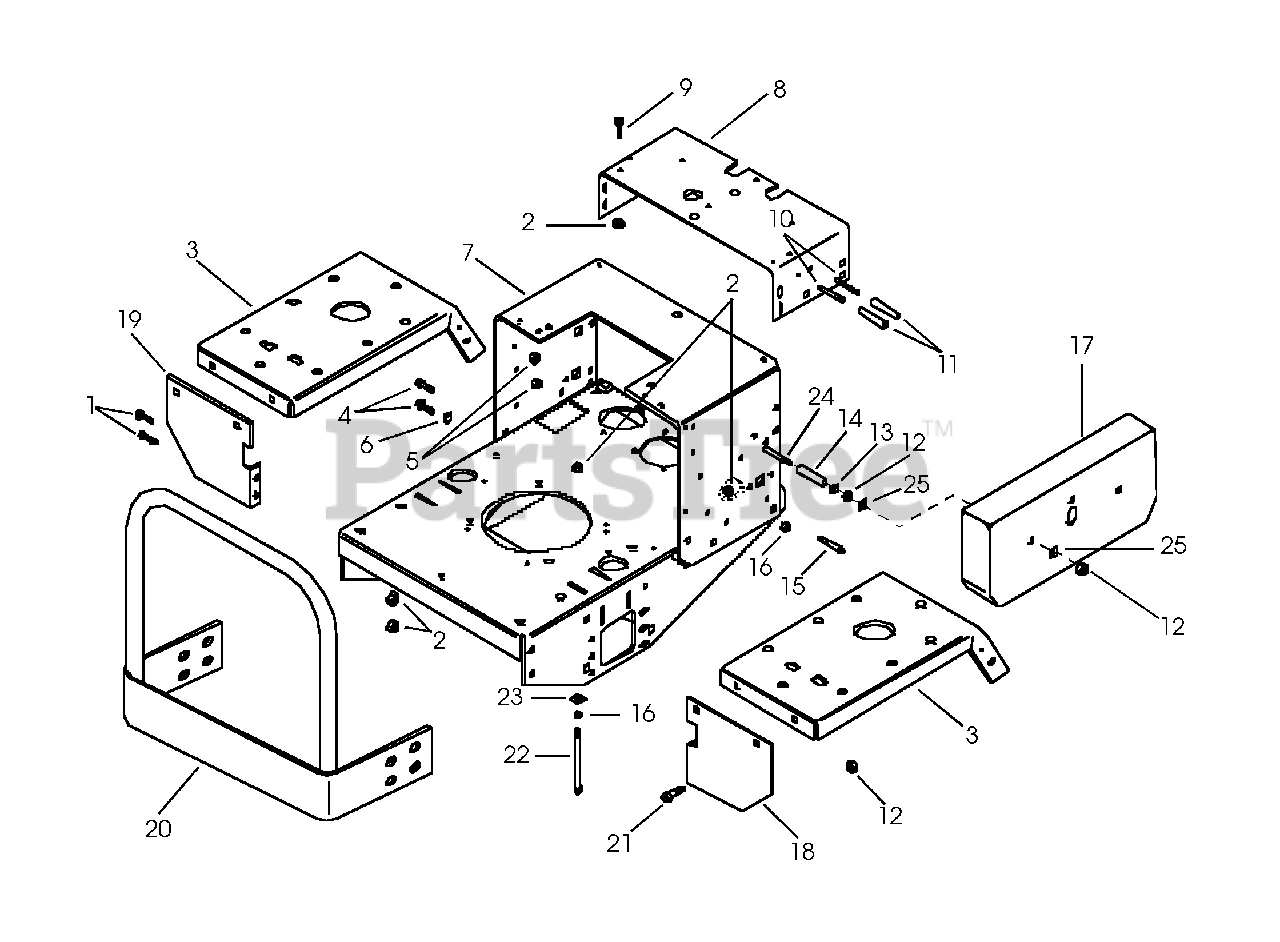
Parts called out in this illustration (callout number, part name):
1	Bolt-Hex .38-16 x 1.25 Grade 5
2	Nut-Locking-Center .38-16
4	Bolt-Hex .25-20 x .75 Grade 5
5	Nut-Locking-Center .25-20
6	Washer-Flat-Steel .281 x .620 x .065
7	Weldment-Frame Z
8	Support Control Weldment
9	Bolt-Hex .375-16 x 1.00 Grade 5
10	Bolt-Hex .31-18 x 4.00 Grade 5
11	Spacer-Split-Rolled
12	Nut-Locking-Center .31-18
13	Washer-Flat-Steel .344 x .688 x .065
14	Spacer-Split-Rolled
15	Bolt-Hex .38-16 x 3.00 Grade 5
16	Nut-Hex .38-16
17	Guard-Linkage
18	Support-Fender Right Hand
19	Support-Fender Left Hand
20	Weldment-Rear Guard
21	Bolt-Hex .31-18 x .75 Grade 5
22	Bolt-Hex .38-16 x 4.00 Grade 5
23	Washer-Flat-Steel .406 x .812 x .065
24	Bolt-Hex .31-18 x 3.75
25	Washer-Flat-Steel .328 x .875 x .062
